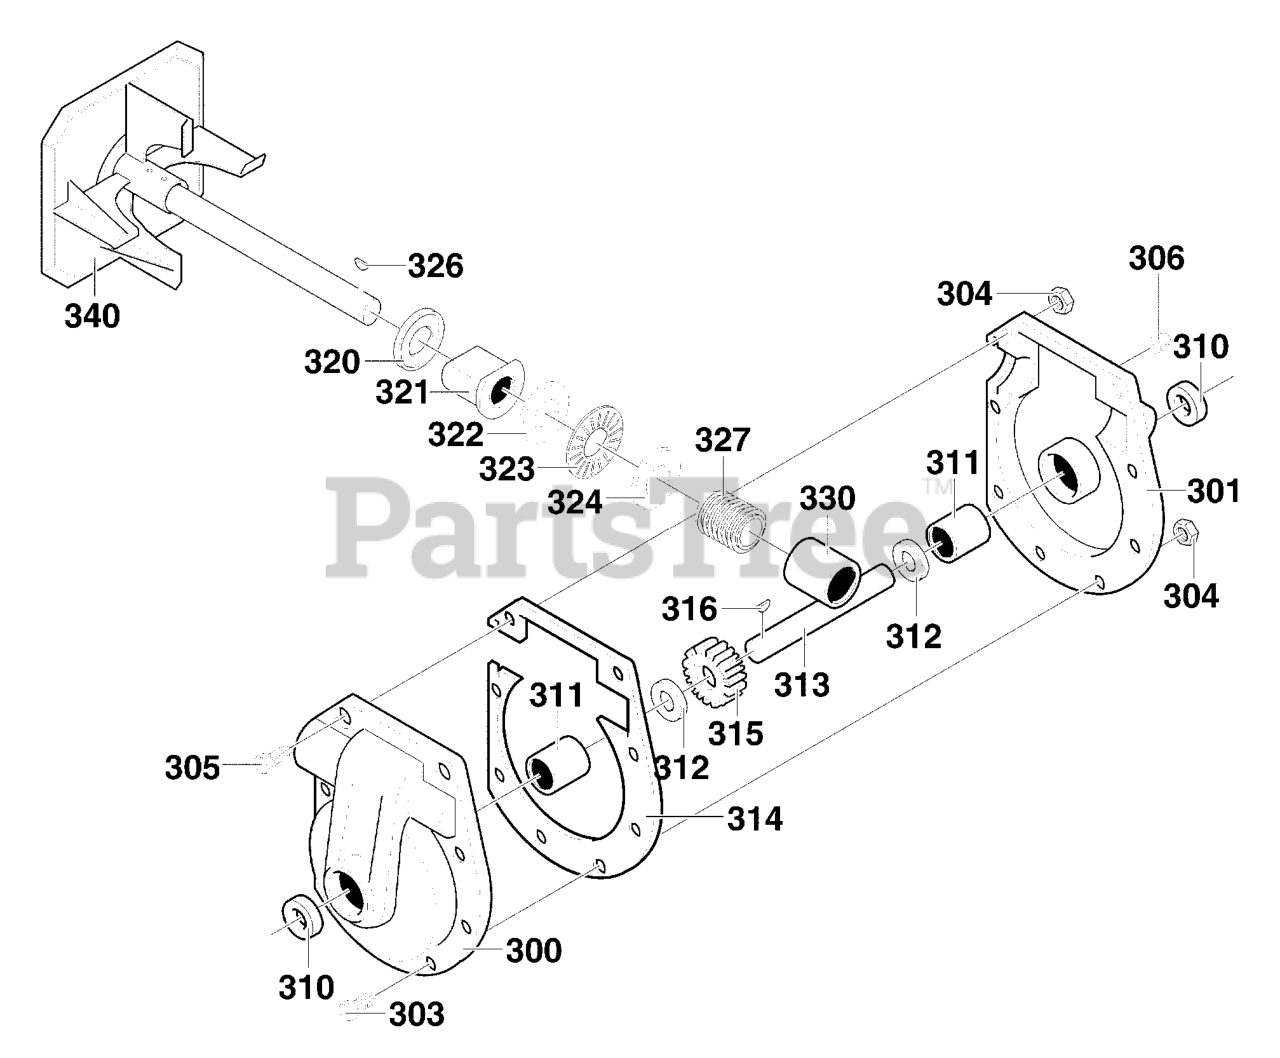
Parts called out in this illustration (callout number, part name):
300	CASE, GEAR RH
301	CASE, GEAR LH
303	SCREW, 5/16-24 x 1.00
304	NUT, 5/16-24 HEXWDFLLK
305	SCREW, 5/16-24 x 1.50
306	PLUG, PIPE
310	SEAL, OIL
311	BEARING, SLEEVE
312	WASHER, FLAT 1.00 x 1.54 x .09
313	SHAFT, AUGER
314	GASKET, GEAR BOX
315	GEAR, WORM
316	KEY, WOODRUFF #91
320	RING, QUAD
321	BEARING, FLANGE
322	WASHER, FLAT .752X1.24X.093
323	BEARING, ROLL
324	WASHER, FLAT .752X1.24X.093
326	KEY, HI-PRO #606
327	GEAR, WORM
330	BEARING
